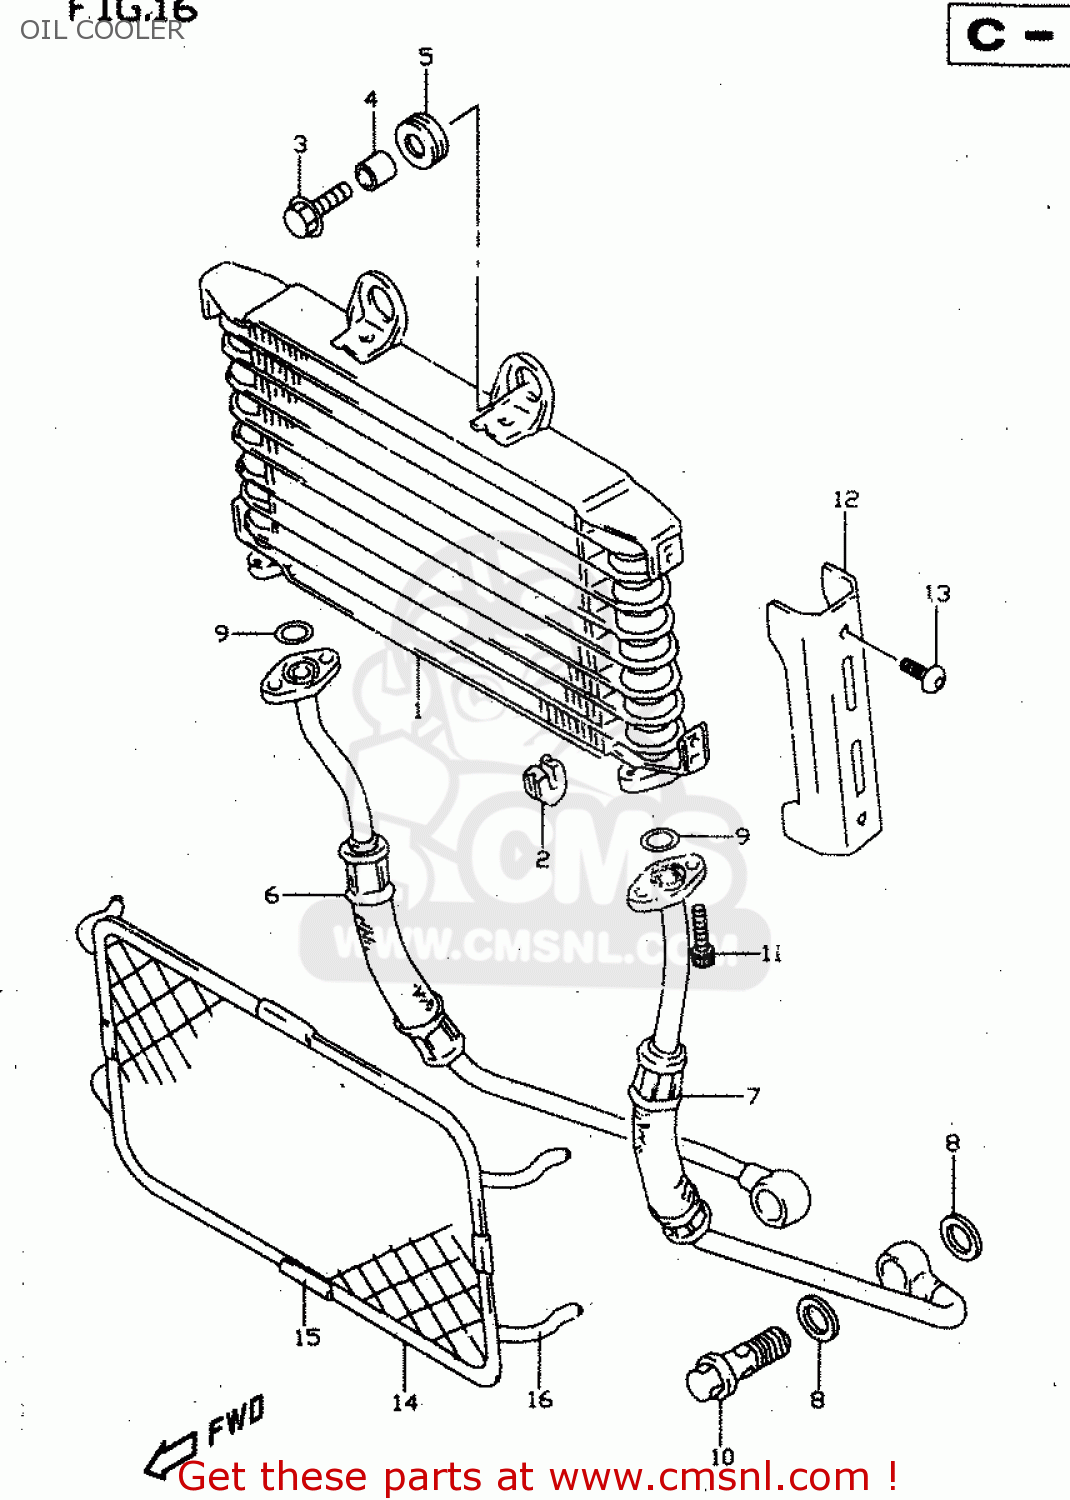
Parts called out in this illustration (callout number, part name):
1	COOLER ASSY,OIL
2	CUSHION,OIL COOLER NO.2
3	BOLT 6X20
4	SPACER(6.5X10X10)
5	CUSHION
6	HOSE, OIL COOLER RH
7	HOSE, OIL COOLER LH
8	GASKET(16X22X2) (NAS)
9	O RING(D:2.4,ID:11.8)
10	BOLT UNION
11	BOLT,OIL FILLE
12	COVER,OIL COOLER
13	SCREW(6X12)
14	GUARD, OIL COOLER
15	PROTECTOR,CTR
16	HOSE(3X5X600)
